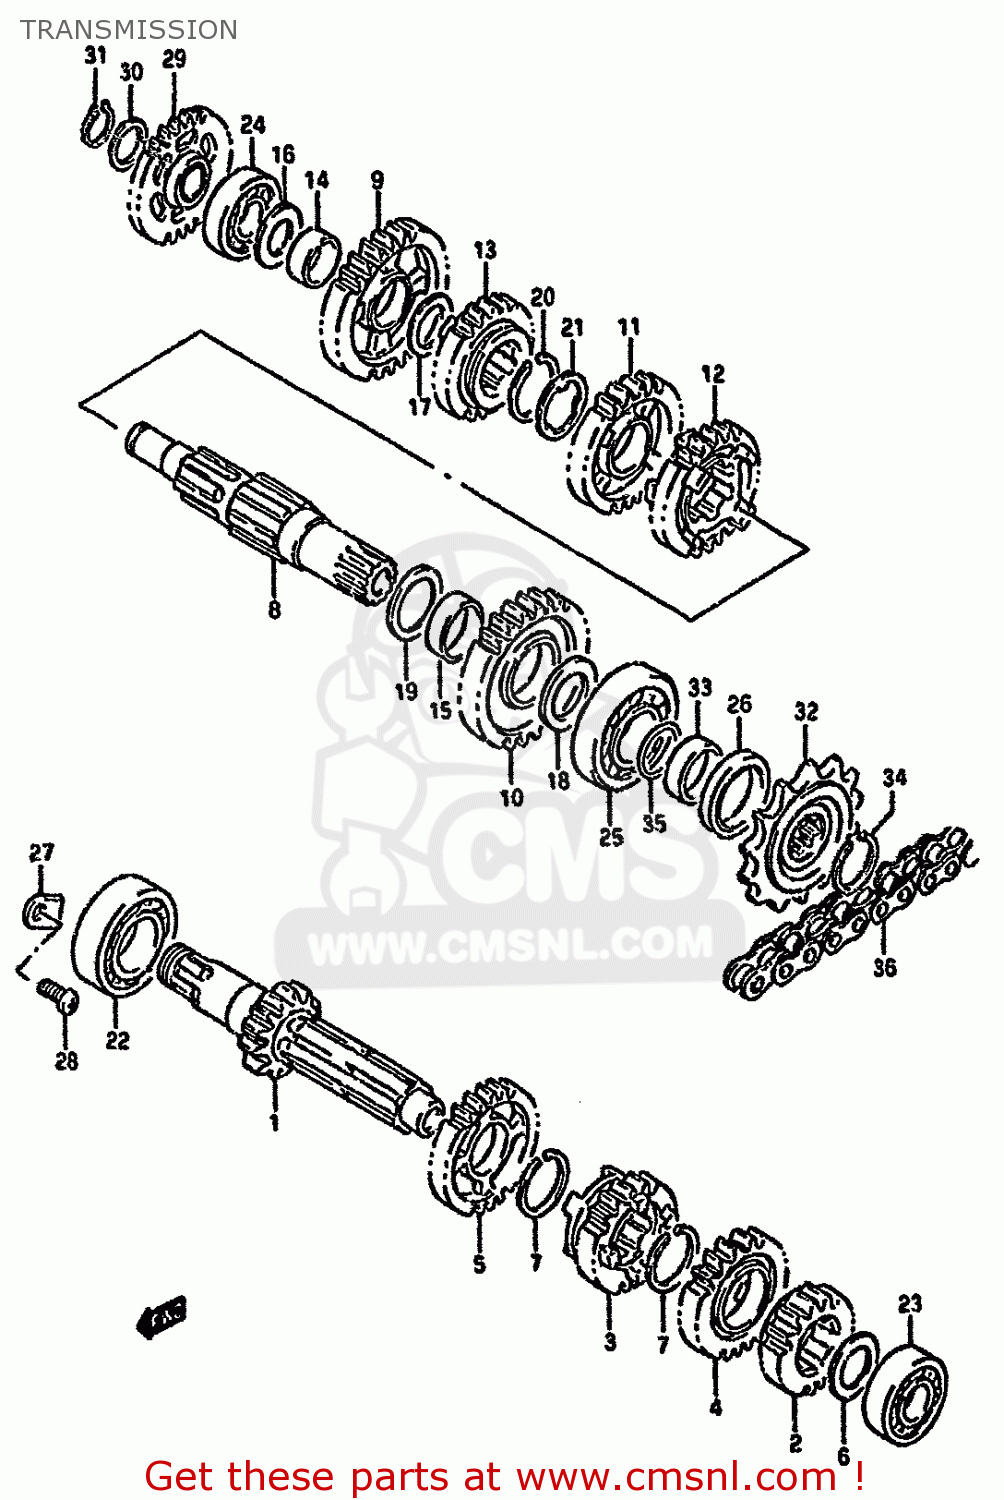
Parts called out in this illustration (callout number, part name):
1	SHAFT,COUNTER(NT:14)
2	GEAR,2ND DRIVE(NT:15)
3	GEAR,THIRD DRIVE (NT:16)
4	GEAR,FOURTH DRIVE (NT:22)
5	GEAR,5TH DRIVE(NT:22)
6	WASHER,THRUST
7	CIRCLIP
8	SHAFT,DRIVE
9	GEAR,1ST DRIVEN(NT:32)
10	GEAR,2ND DRIVEN(NT:26)
11	GEAR,3RD DRIVEN(NT:22)
12	GEAR,FOURTH DRIVEN (NT:24)
13	GEAR,FIFTH DRIVEN (NT:19)
14	BUSH(20X24X10)
15	BUSH(25X28X10)
16	WASHER,THRUST
17	WASHER
18	THRUST WASHER
19	WASHER
20	CIRCLIP
21	WASHER,LOCK
22	BEARING(25X52X15)
23	BEARING(17X40X12)
24	BEARING(17X40X12)
25	BEARING(22X56X15)
26	SEAL,OIL(28X38X6)
27	RETAINER
28	SCREW
29	GEAR,KICK STARTER IDLE(NT:27)
30	SHIM
31	CIRCLIP
32	SPROCKET,ENGINE
33	SPACER,ENGINE SPROCKET
34	CIRCLIP
35	O RING(D:1.9,ID:21.8)
36	CHAIN,DRIVE
